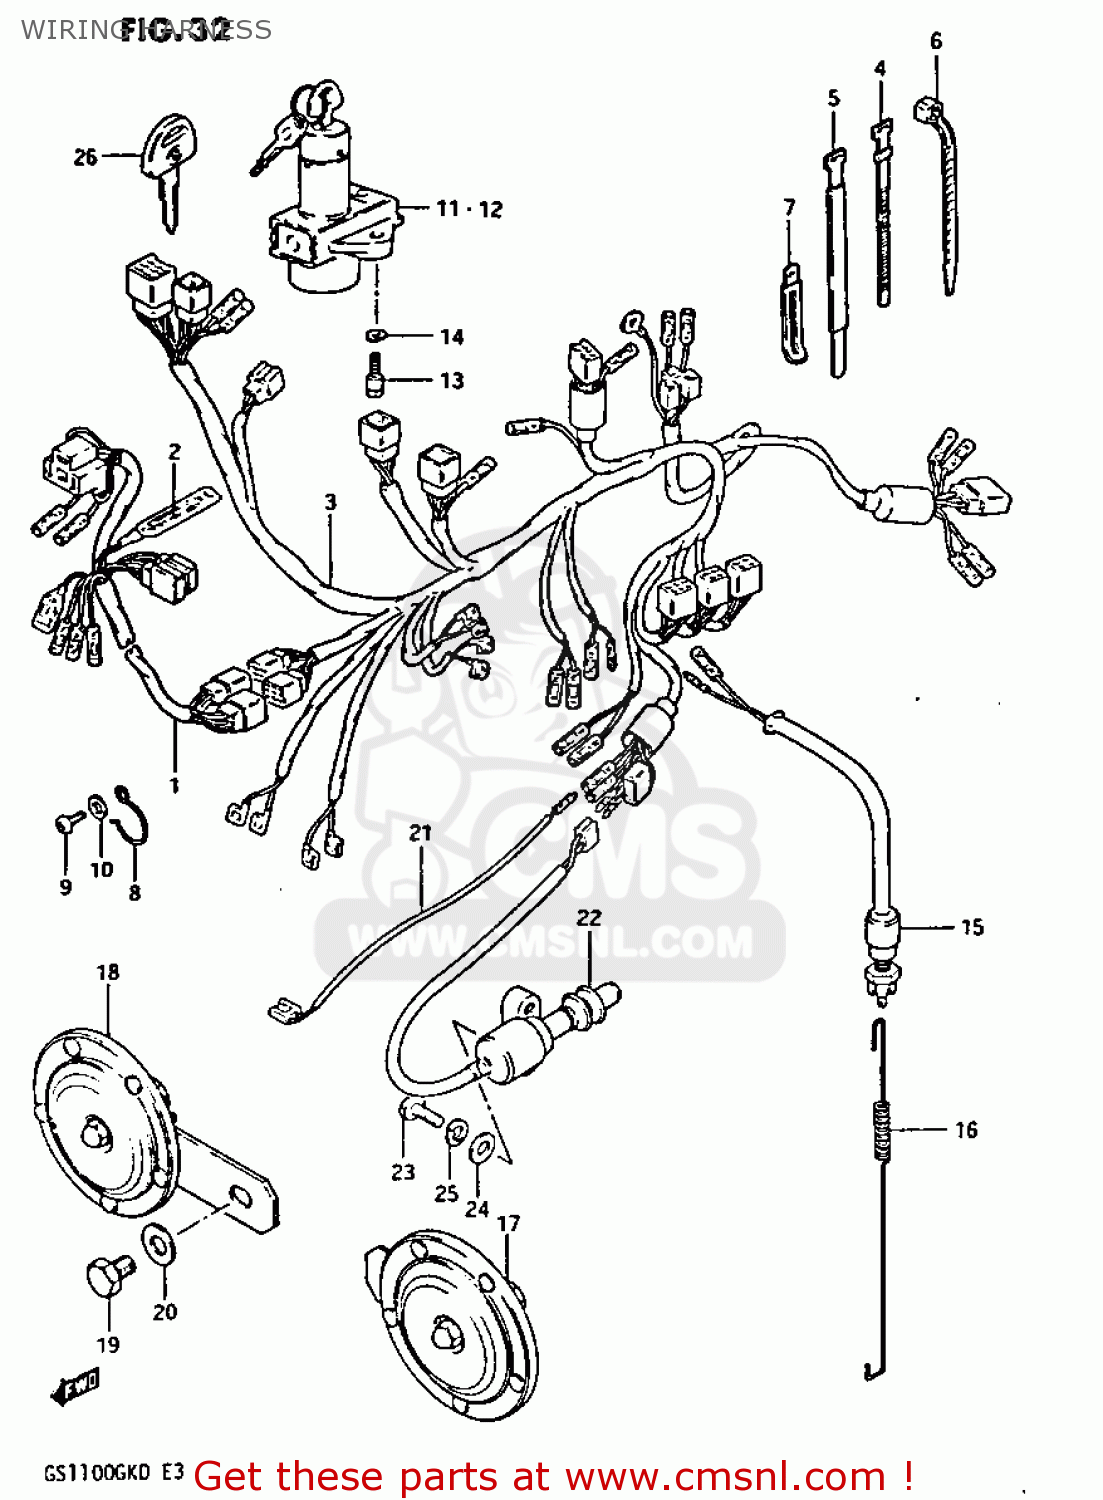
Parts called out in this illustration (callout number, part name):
1	HARNESS,WIRING NO.1
2	DIODE
3	HARNESS,WIRING NO.2
4	CLAMP(L:120)
5	CLAMP
6	CLAMP
7	CLAMP
8	CLIP,WIRING HARNESS
9	SCREW 6X12
10	WASHER
11	LOCK ASSEMBLY,STEERING
12	SWITCH ASSEMBLY,IGNITION
13	BOLT
14	WASHER,LOCK
15	SWITCH ASSY,STOP LAMP
16	SPRING
17	HORN ASSEMBLY,LOW PITCH
18	HORN ASSEMBLY,HIGH PITCH
19	BOLT 8X12
20	WASHER
21	WIRE,OIL PRESSURE SWITCH LEAD
22	SWITCH ASSY,SIDE STAND WARN
23	BOLT
24	WASHER
25	LOCK WASHER
26	KEY,BLANK
